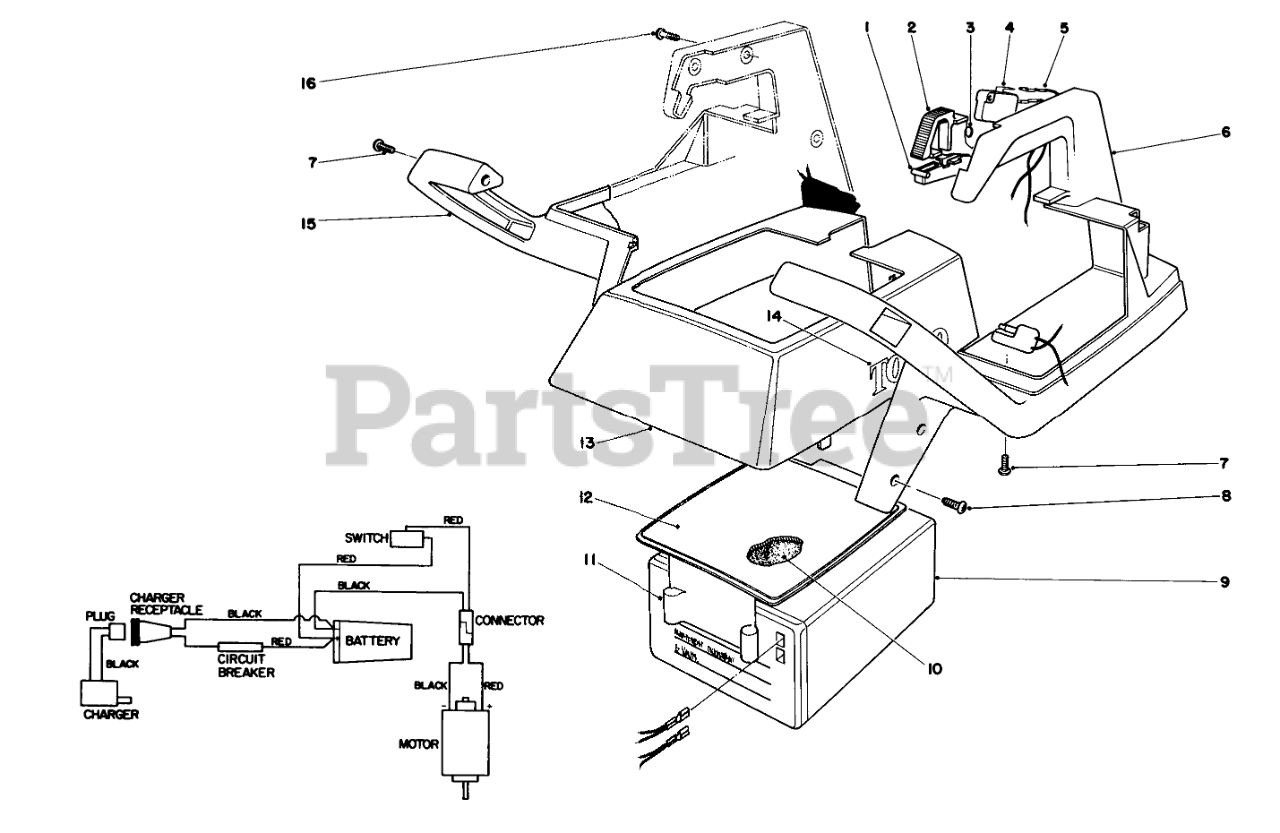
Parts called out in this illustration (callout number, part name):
1	TRIGGER
2	TRIGGER LOCK
3	SPRING
4	Switch
5	Wiring Harness
6	LH BATTERY CASE/HNDL
7	Screw
8	10-16 X .31 SCREW
9	BATTERY
10	FOAM PAD
11	CONTROL PANEL, CL-710
12	DECAL, FRONT PANEL, CSA
13	Cover (Incl. Ref. #14)
14	DECAL - TORO
15	RH BATTERY CASE/HNDL
16	SCREW-PPH
